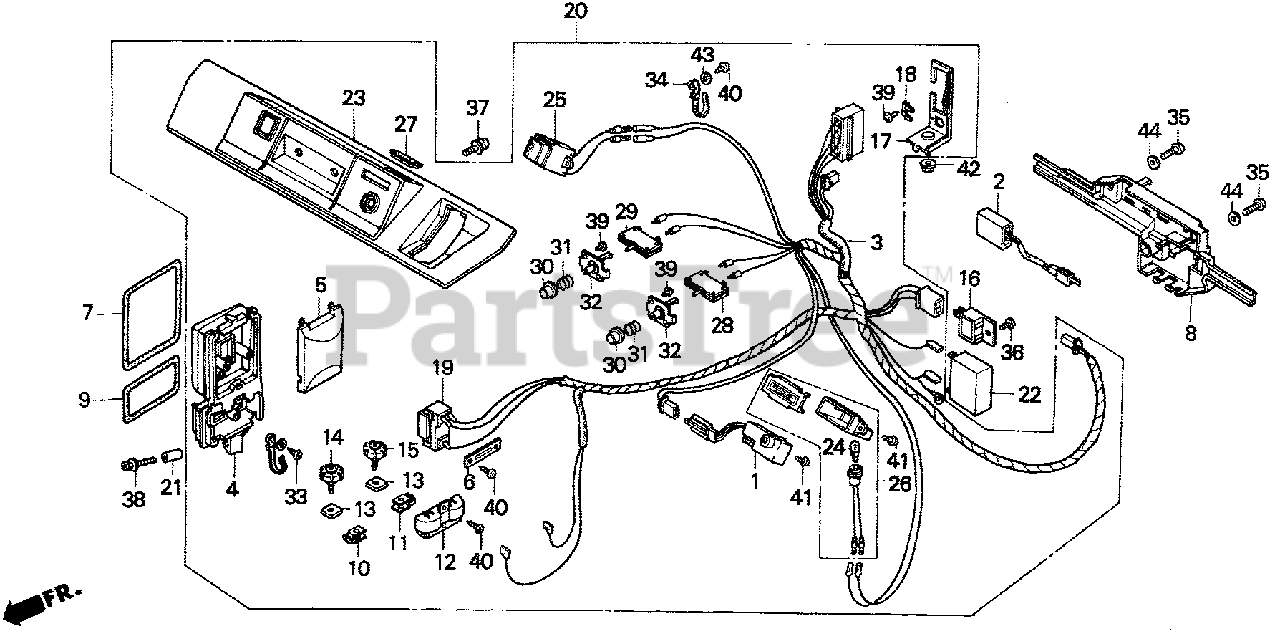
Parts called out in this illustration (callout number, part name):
1	ALERT UNIT, OIL
2	UNIT, IGNITION
3	WIRE HARNESS ASSY.
4	PANEL, RECEPTACLE
5	COVER, RECEPTACLE
6	HOLDER, RECEPTACLE
7	SEAL A, RECEPTACLE PANEL
8	COVER, WIRE HARNESS SETTING
9	SEAL B, RECEPTACLE PANEL
10	CONTACT, D.C. TERMINAL (+)
11	CONTACT, D.C. TERMINAL (-)
12	HOLDER, D.C. TERMINAL
14	KNOB, D.C. TERMINAL (+)
15	KNOB, D.C. TERMINAL (-)
16	DIODE, D.C.
17	PLATE, CONNECTOR SETTING
18	HOLDER, CONNECTOR
19	RECEPTACLE (15A/125V)
20	PANEL ASSY.
21	COLLAR, PANEL
22	CONDENSER
23	PLATE, BASE
24	BULB, WEDGE BASE (6V1.7W) (STANLEY)
25	METER, FREQUENCY
26	SOCKET ASSY., LAMP
27	CAP, PILOT LAMP
28	PROTECTOR, D.C. CIRCUIT (12A)
29	PROTECTOR, A.C. CIRCUIT (5A)
30	CAP, BREAKER
31	SPRING, RETURN
32	HOLDER, BREAKER
33	SCREW, TAPPING (3X14)
34	CLIP, HARNESS
35	SCREW, PAN (5X8)
36	SCREW, PAN (5X10)
37	SCREW-WASHER (6X10)
38	SCREW-WASHER (5X25)
39	SCREW, TAPPING (3X8)
40	SCREW, TAPPING (4X10)
41	SCREW, TAPPING (4X16)
42	NUT, FLANGE (5MM)
43	WASHER, PLAIN (4MM)
44	WASHER, PLAIN (5MM)
